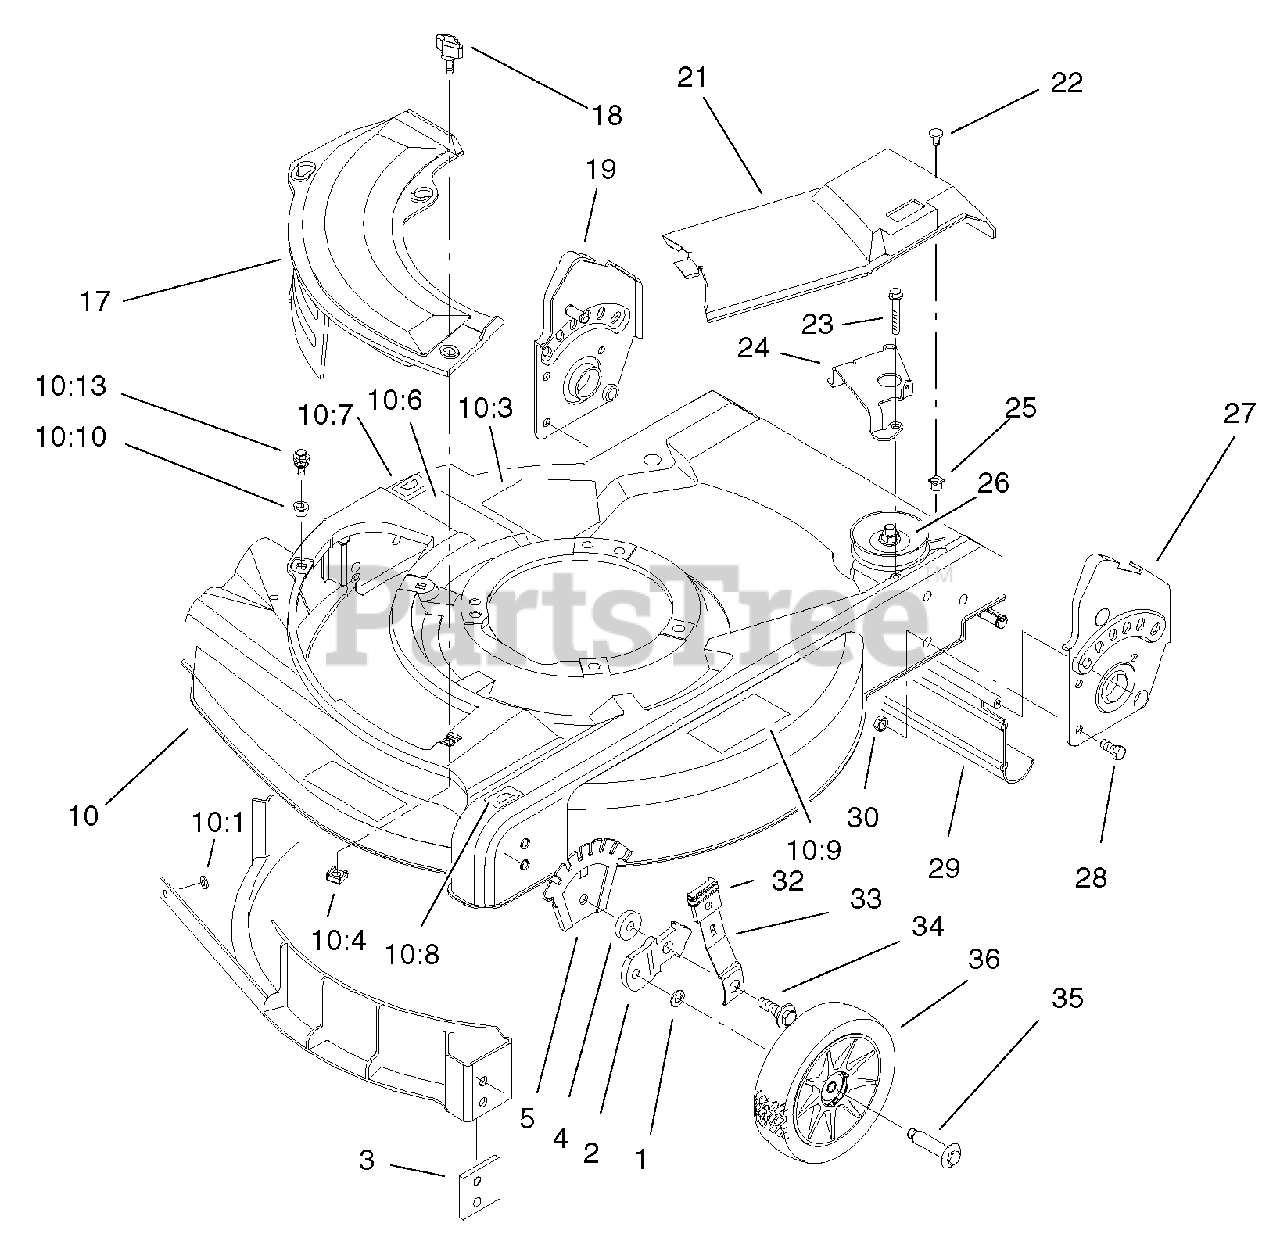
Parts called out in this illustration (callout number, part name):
2	Bracket-Height Adjustment, Wheel
3	Plate-Baffle
4	Washer-Wheel
5	Plate-Height, Adjustment
10	Deck ASM
10:1	Washer-Flat
10:3	Decal-Danger
10:4	Nut-Cage
10:6	Decal-Warning
10:7	Decal-HOC, RH
10:8	Decal-HOC, LH
10:9	Decal-Warning
10:10	Grommet-Plastic
10:13	Screw-Sems
17	Plate-Mulch
19	Bracket ASM-Right
21	Cover-Drive
23	Screw-HWHTF
24	Guide-Transmission
25	Grommet
26	Gear Case ASM
27	LH Bracket ASM
28	Screw-HH
29	Shield-Trailing
30	Nut-Lock, NI
32	Knob-Lever, Height Adjustment
33	Arm-Front Spring
34	Bolt-Shoulder
35	Bolt-Shoulder
36	Wheel & Tire ASM
